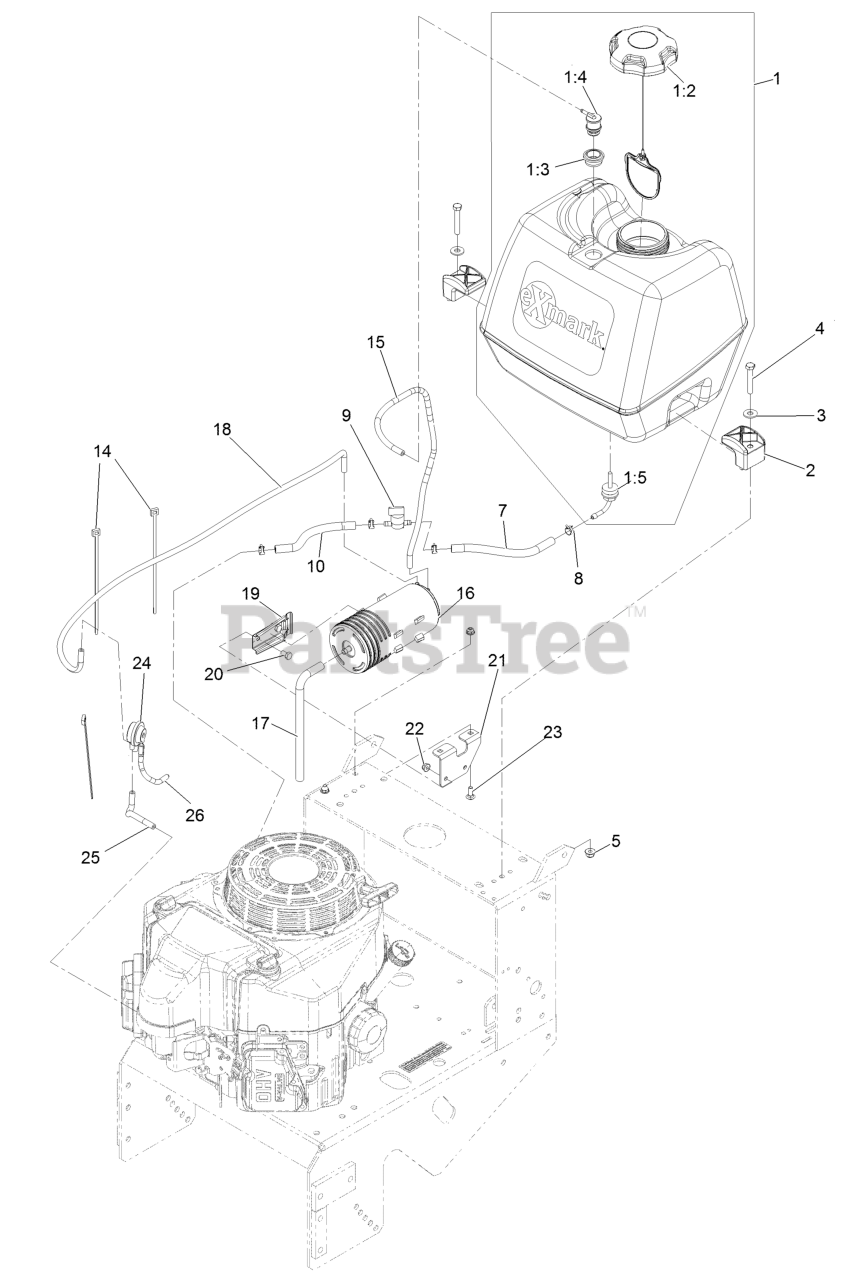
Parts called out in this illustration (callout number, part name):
1	ASM, FUEL TANK
1:3	GROMMET
1:4	VALVE-VENT, FUEL
1:5	FITTING-FUEL, BULKHEAD
3	WASHER-FLAT
4	SCREW-HH
5	NUT-HF, NI
7	HOSE-FUEL
8	CLAMP-HOSE
9	VALVE-FUEL
10	HOSE-FUEL
14	TIE-PLASTIC
15	HOSE-VENT
16	CANISTER-CARBON, 800CC
17	HOSE-VENT, CANISTER
18	HOSE-VENT, FORMED
19	BRACKET-CANISTER, CARBON
20	SCREW-HH
21	BRACKET-CANISTER, CARBON
23	BOLT-CARR
24	VALVE-CONTROL, VACUUM
25	HOSE-VENT, FORMED
26	HOSE-VENT, FORMED
